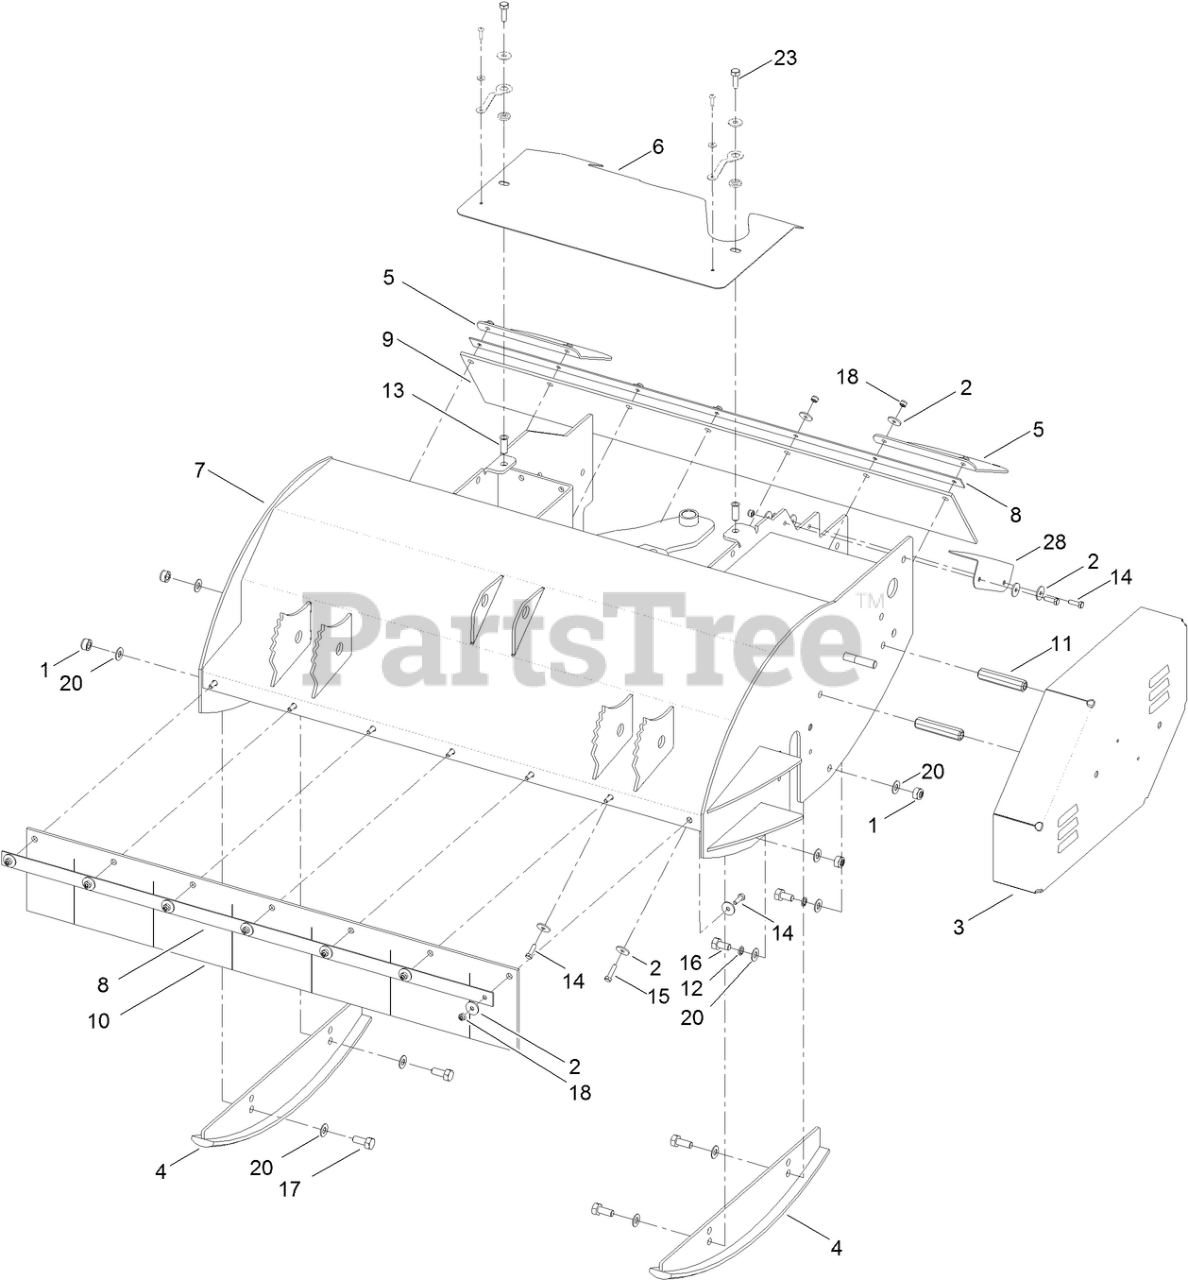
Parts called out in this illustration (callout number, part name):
1	NUT-HEX, NI
2	WASHER
3	COVER-BELT DRIVE
4	SKID-SIDE
5	GUARD-FOOT
6	GUARD-DRIVE, GEARBOX
7	FRAME-MAIN
8	BRACKET-DEFLECTOR
9	RUBBER-DEFLECTOR
10	RUBBER-DEFLECTOR SLITTED
11	NUT-ADJUSTER
12	WASHER-LOCK
13	RIVET-BLIND BUSHING
14	SCREW-HH
15	SCREW-HH
16	SCREW-HH
17	SCREW-HH
18	NUT-NYLOC
20	WASHER-PLAIN
23	SCREW-HH
28	BRACKET-ADAPTOR
